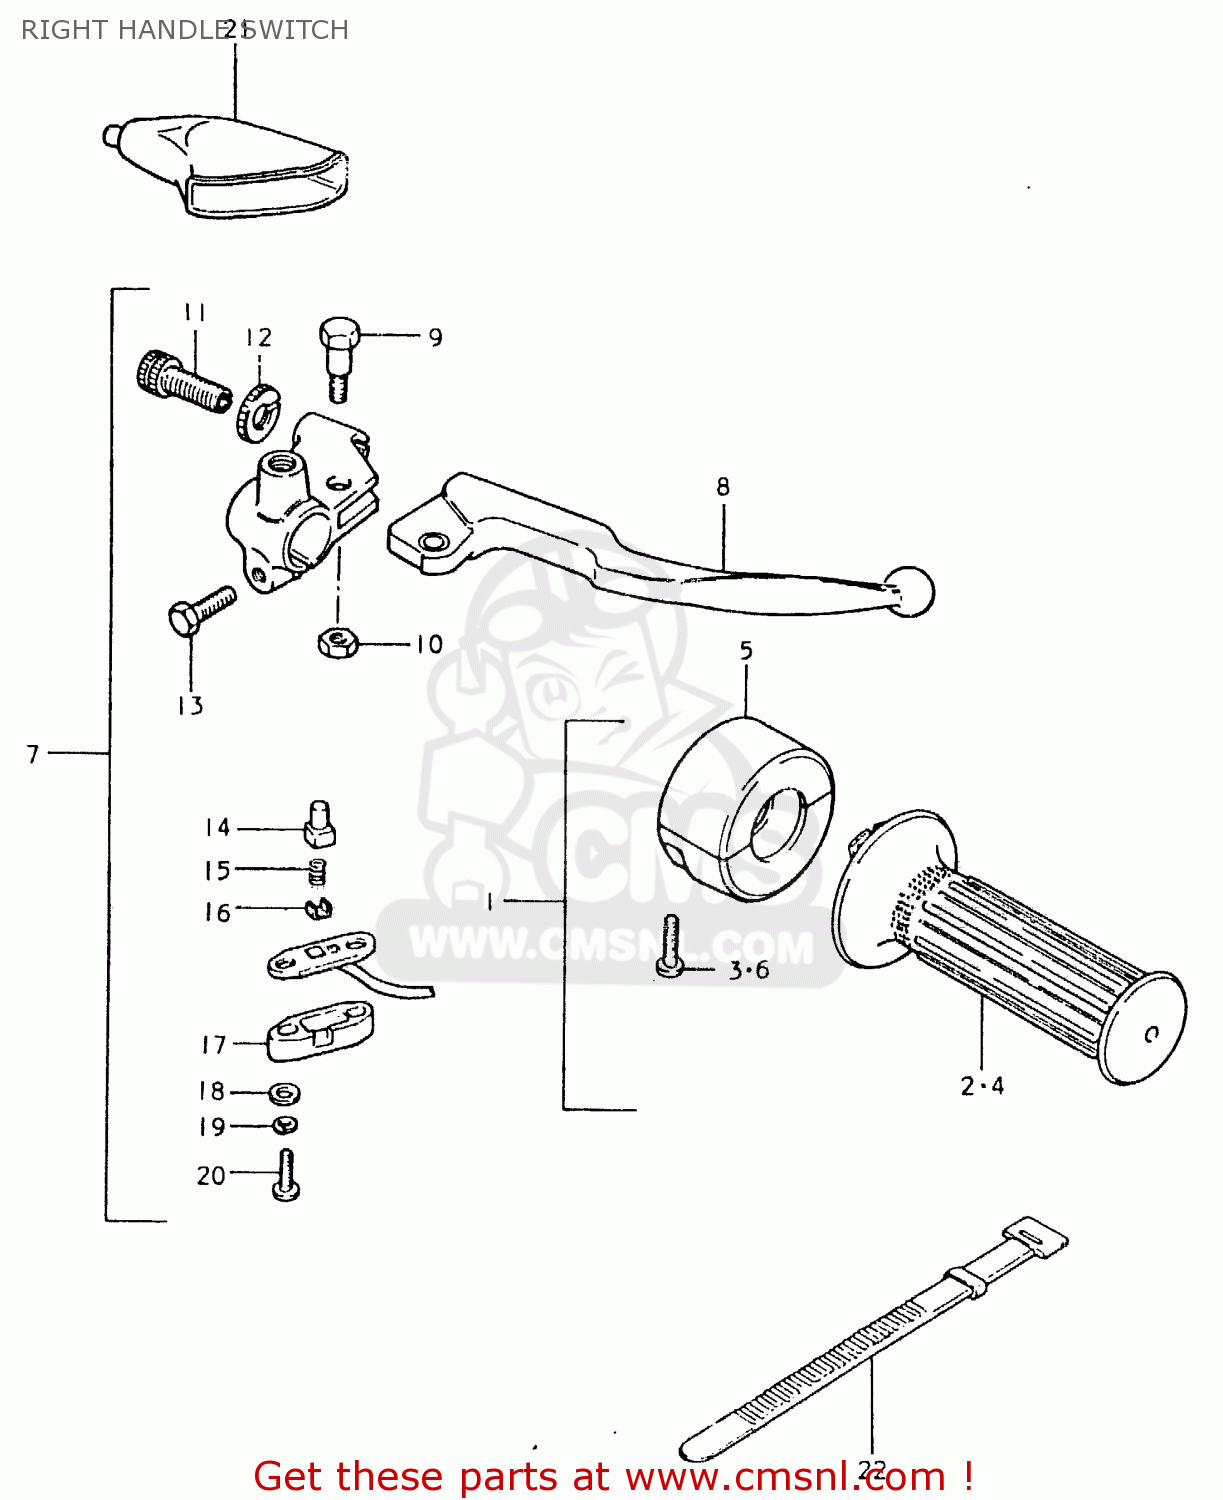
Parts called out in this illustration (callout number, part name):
1	GRIP ASSY, THROTTLE
2	GRIP,THROTTLE
3	SCREW
4	GRIP,THROTTLE
5	CASE ASSY,THROTTLE
6	SCREW
7	LEVER ASSY,BRAKE
8	LEVER,BRAKE
9	BOLT,LEVER
10	NUT 6MM
11	ADJUSTER,CABLE
12	NUT,CABLE ADJUSTER
13	BOLT
14	HOLDER
15	SPRING
16	PLATE
17	COVER,FR BK TERMINAL BASE
18	WASHER
19	LOCK WASHER
20	SCREW
21	COVER,CLUTCH LEVER
22	CLAMP(L:120)
